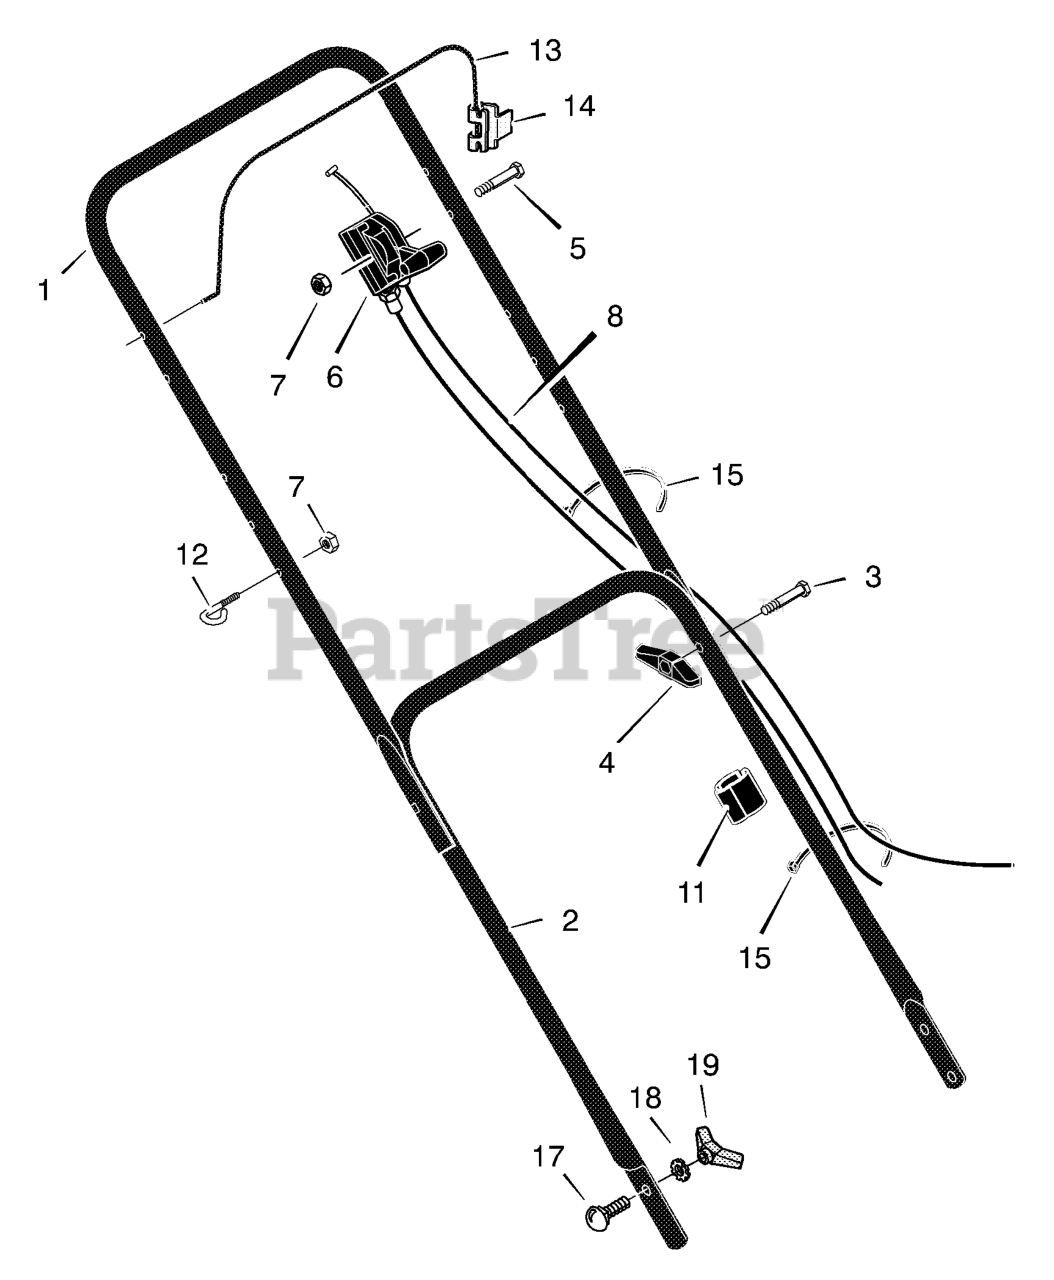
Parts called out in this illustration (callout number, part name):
1	Handle, Upper (Black)
2	Handle, Lower (Black)
4	Knob, Plastic
6	Throttle Control
7	Locknut
8	Engine Stop Cable
11	Clip, Cable
12	Guide, Rope
13	Lever, Engine Stop
14	Bracket, Stop Lever
15	Fastener, Cable
17	Bolt, Carriage
18	Washer
19	Knob, Plastic
